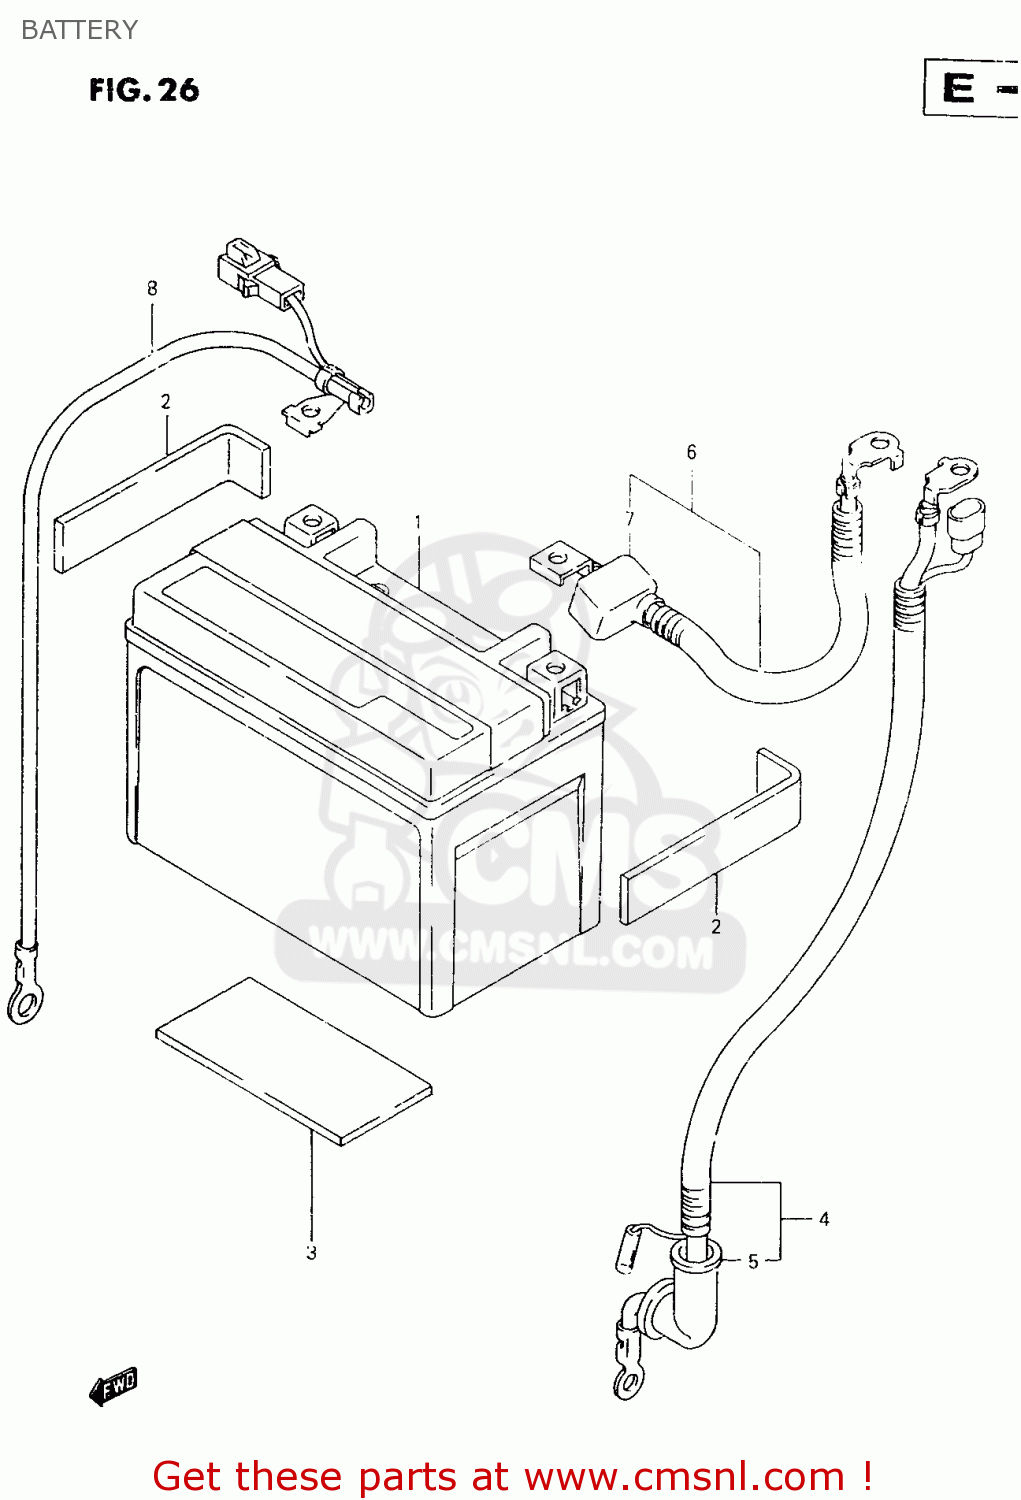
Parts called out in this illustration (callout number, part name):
1	BATTERY ASSEMBLY (12V) FTX
2	PROTECTOR(170X95X3.0)
3	PROTECTOR(170X95X3.0)
4	WIRE,STARTER MOTOR LEAD
5	CAP,STARTER MOTOR LEAD
6	WIRE,BATTERY PLUS LEAD
7	CAP,BATTERY PLUS
8	WIRE,BATTERY MINUS
